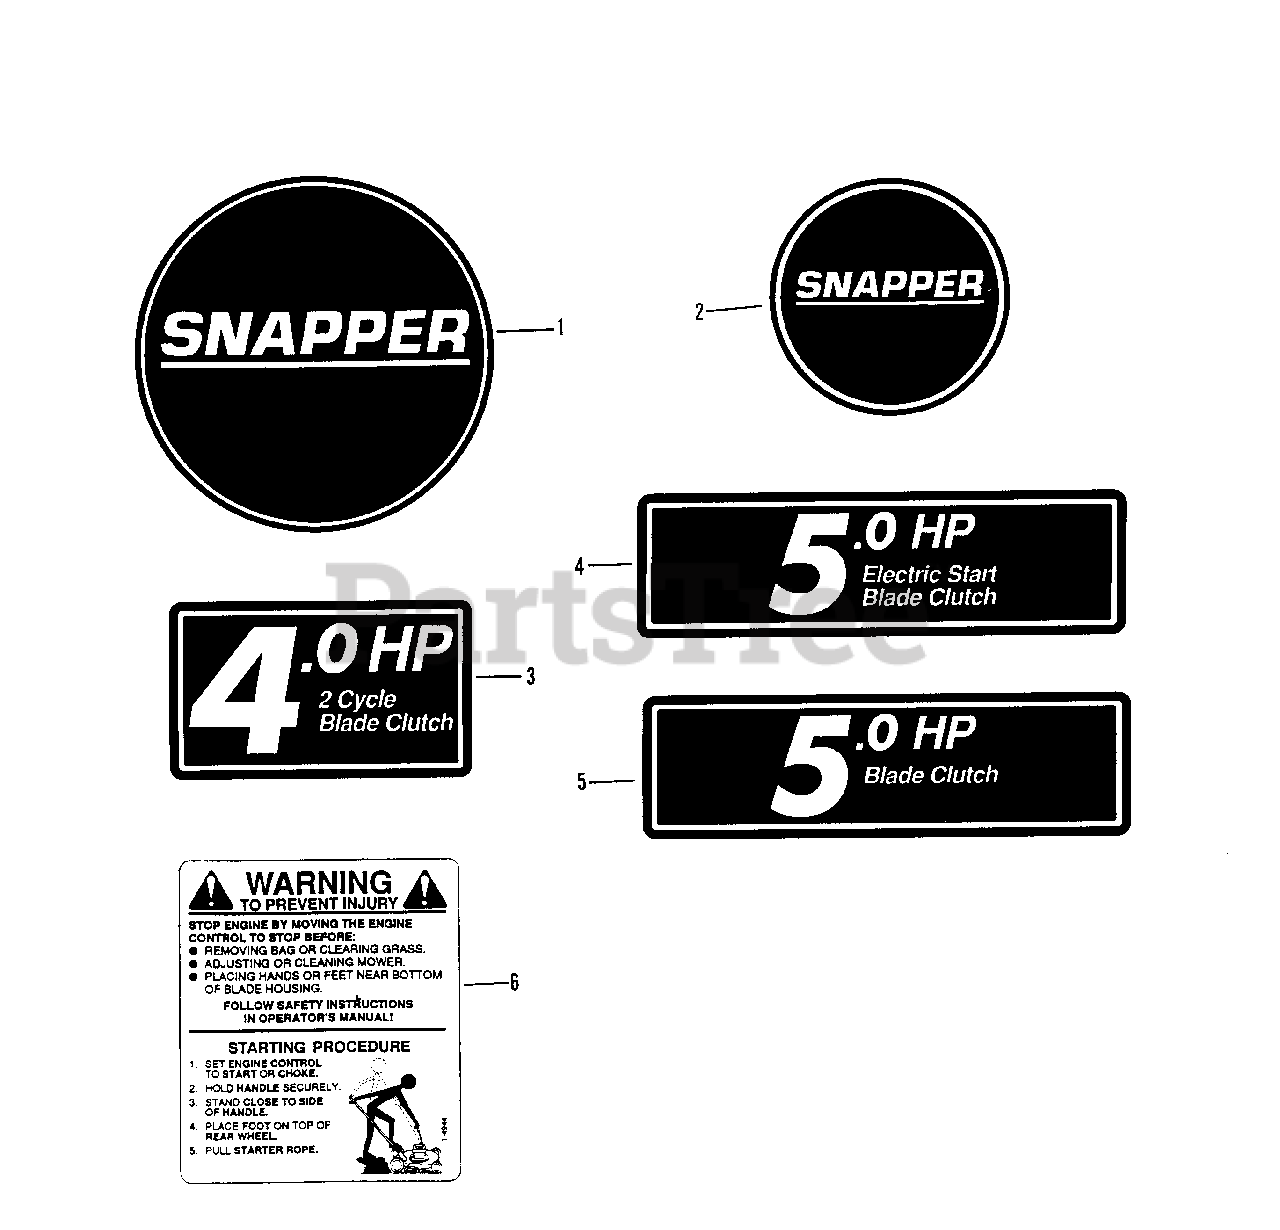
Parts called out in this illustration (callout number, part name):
1	DECAL, Recoil Housing (3.85 O.D.)
2	DECAL, Recoil Housing (2.58 O.D.)
3	DECAL, 4.0HP 2-Cycle
4	DECAL, 5.0HP Electric Start
5	DECAL, 5.0HP
6	DECAL, Warning
